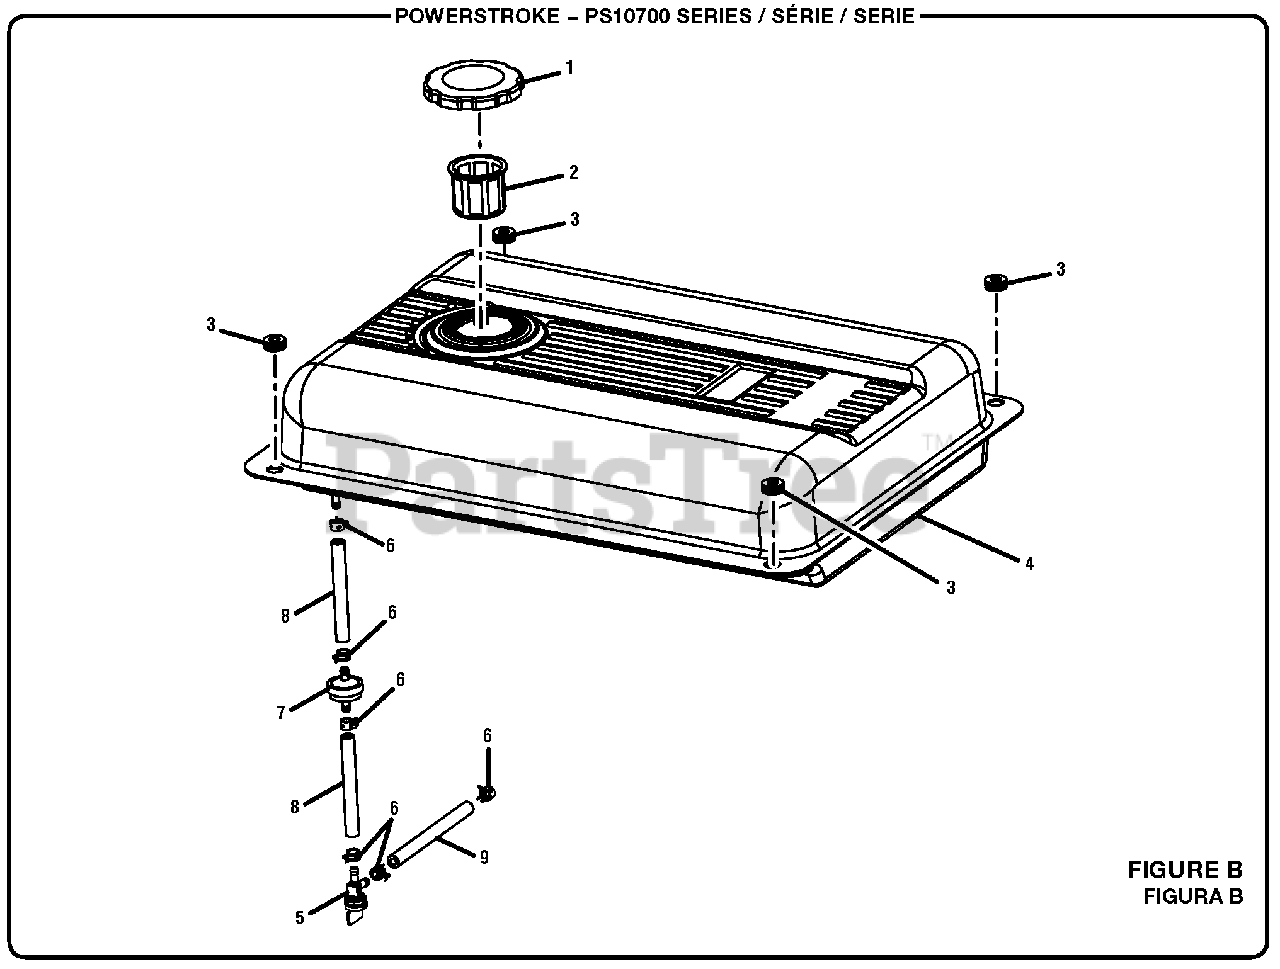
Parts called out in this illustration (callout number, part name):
1	Fuel Tank Cap
2	Fuel Tank Screen
3	Bushing w/Insert
4	Fuel Tank
5	Fuel Valve
6	Fuel Line Clamp (1/2 in.)
7	Fuel Line Filter
8	Fuel Line (1/4 in.)
9	Fuel Hose (1/4 in.)
